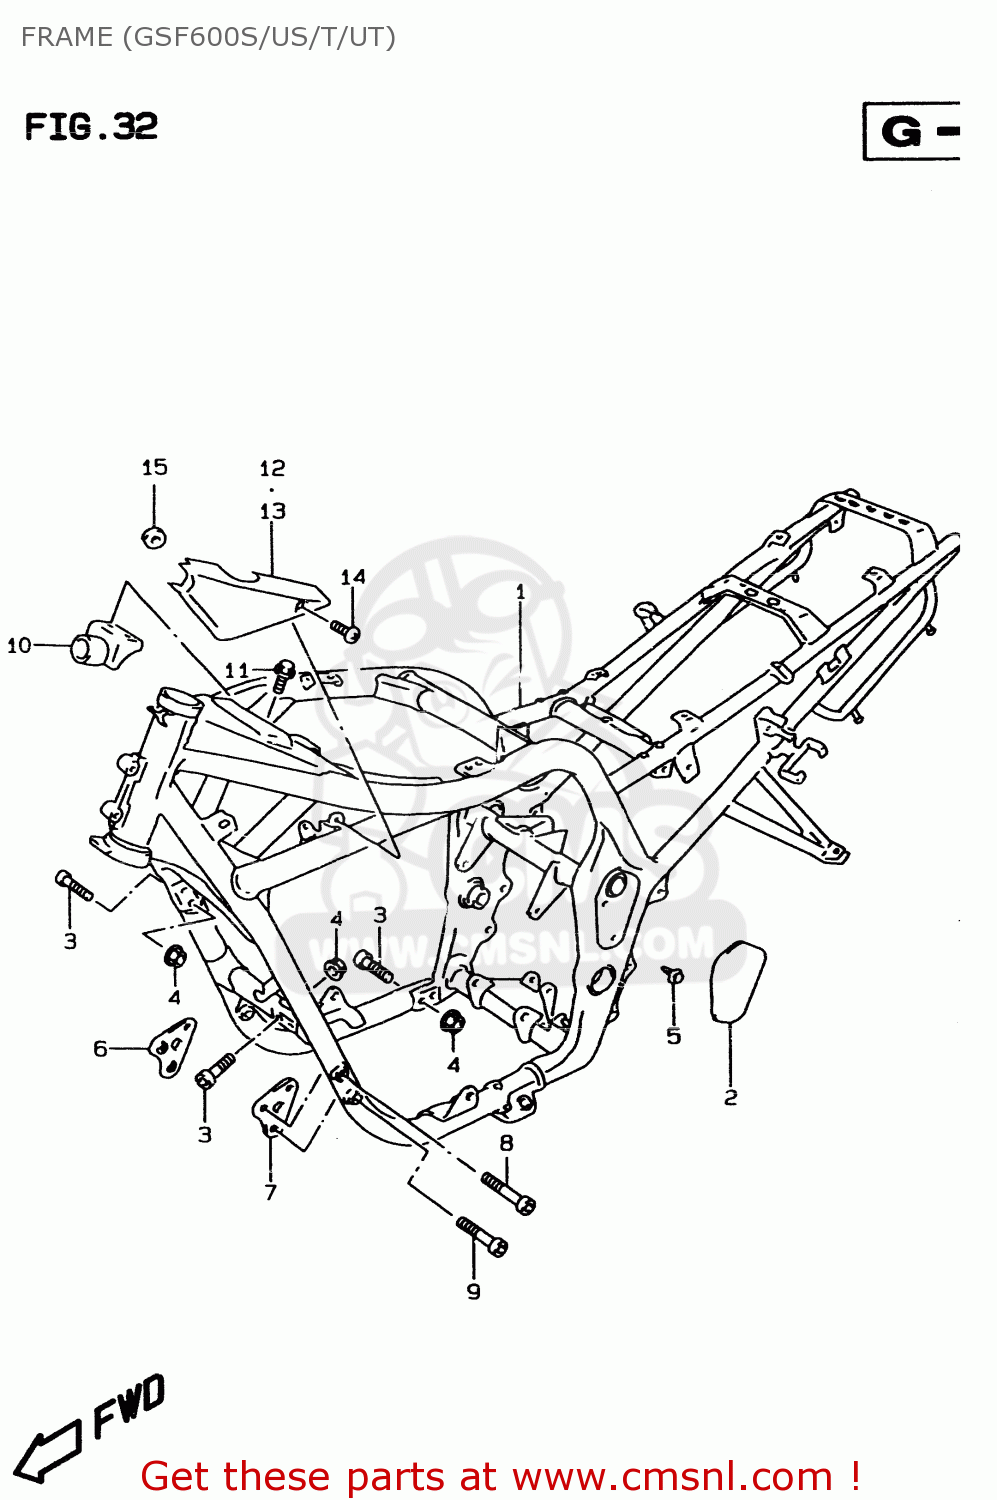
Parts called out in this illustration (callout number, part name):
1	FRAME COMP
2	COVER,FRAME BODY,R
3	BOLT(10X33)
4	NUT
5	CLIP
6	PLATE,ENG MNT,
7	PLATE,ENG MNT,
8	BOLT
9	BOLT
10	DAMPER,FRAME
11	BOLT
12	COVER,FRAME HEAD,R
13	COVER,FRAME HEAD,L
14	SCREW(5X12)
15	CUSHION
